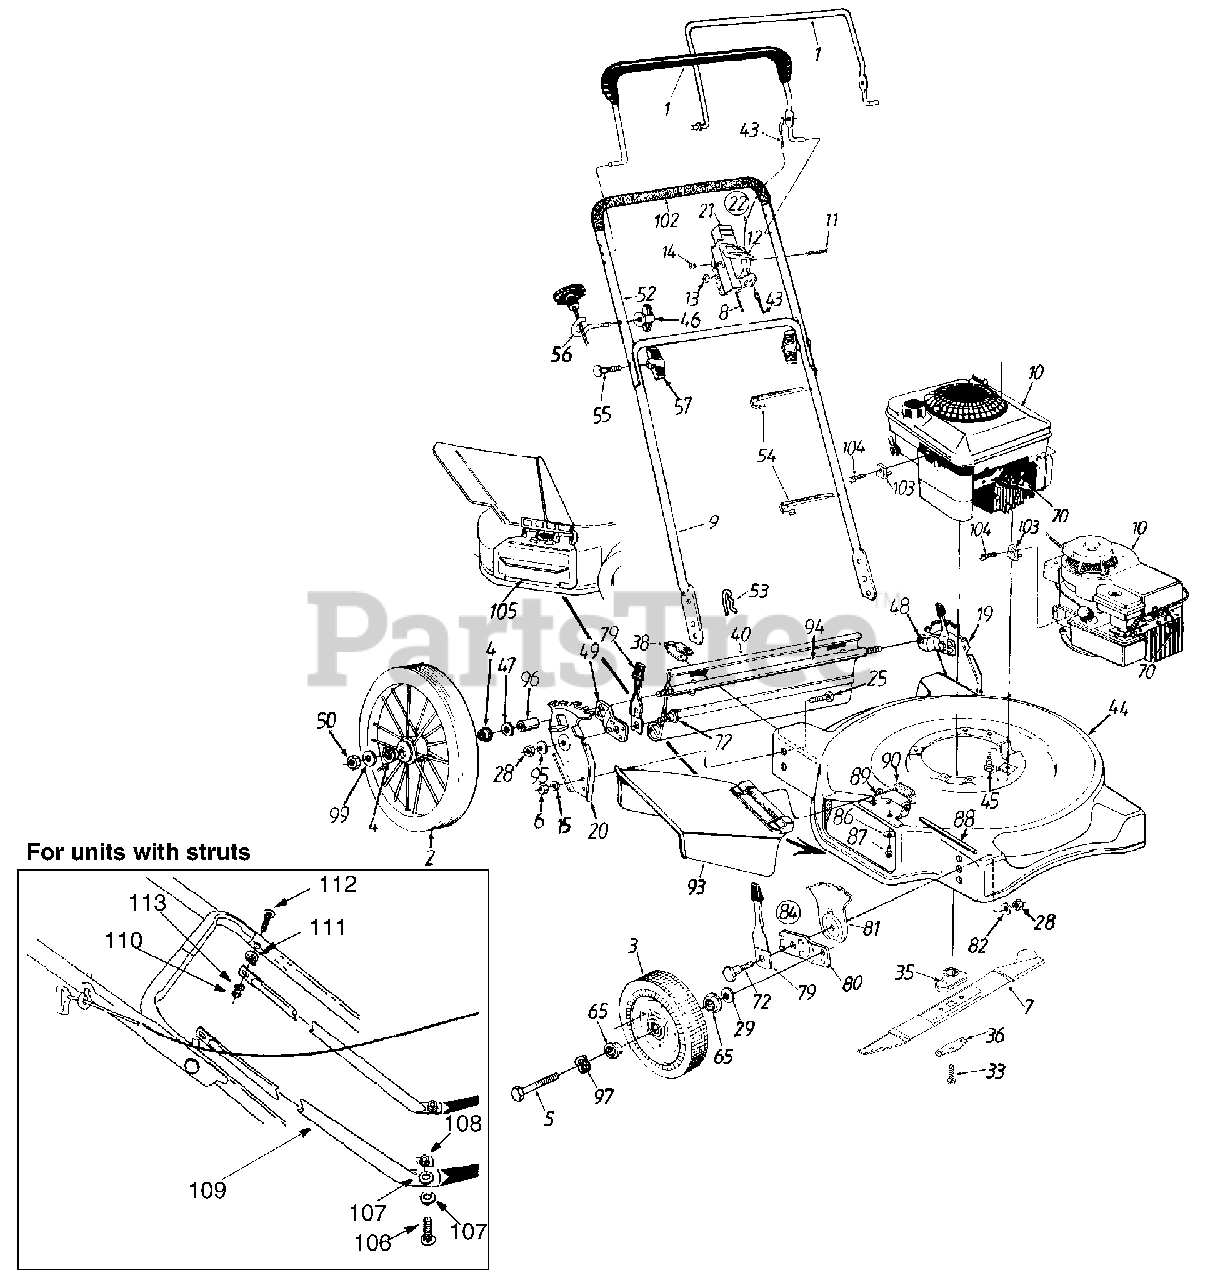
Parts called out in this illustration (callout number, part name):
2	Rear Wheel Assembly - 8 Spoke - Oyster
2	Rear Wheel Assembly - Aero Gray w/Ball Brgs.
2	Rear Wheel Assembly - Steel Spoke w/Ball Bearings
3	Front Wheel Assy Wheels w/o Bearings - (Gray) Bar Tread
3	Front Wheel Assy Wheels w/o Bearings - (Gray w/Hub Cap) Bar Tread
3	Front Wheel Assy Wheels w/o Bearings - (Beige) Bar Tread
3	Front Wheel Assy Wheels w/Plastic Brgs. - Aero Gray Bar Tread
3	Front Wheel Assy Wheels w/Plastic Brgs. - White "T" Tread
3	Front Wheel Assy Wheels with Ball Brgs. - Gray "T" Tread
3	Front Wheel Assy Wheels with Ball Brgs. - Gray "S" Wave Tread
3	Front Wheel Assy Wheels with Ball Brgs. - Gray Link Tread
4	Bearing
5	Front Axle Bolt
6	Hex Nut 3/8-24 Thd.
7	Blade 22"
8	Throttle Control Wire 51"
10	Engine
11	Oval C-Sunk Mach. Scr.
12	Throttle Lever
13	Spring Lever
14	Hex Lock Nut 1/4-20 Thd.
22	Throttle Box Comp.
25	Ribbed Neck Bolt 3/8-24 x 80"
28	Hex Nut 3/8-16 Thd.
29	Bell Washer
33	Hex Bolt 3/8-24 x 1.5"
35	Blade Adapter Kit
36	Blade Bell Support
38	Hinge Clip
40	Rear Flap Ass'y.
43	Control Cable - 39"
46	Handle Knob 1/4-20 Thd.
47	Wave Washer
48	Pivot Bar—L.H.
49	Pivot Bar—R.H.
50	Hex Jam Nut 3/8-16 Thd.
54	Cable Tie
55	Curved Hd. Bolt 5/16-18 x 2"
56	Rope Guide
57	Hand Knob
70	Spark Plug Boot
72	Shoulder Bolt
79	Spring Lever Assembly w/ knob
80	Pivot Bar
81	Height Adj. Plate
82	Bell Washer
84	Front Height Adjustment Assembly Comp.-R.H.
86	Bell Washer
87	Hex Washer Head Tap Scr. 1/4-20 x .5"
88	Hinge Pin
89	Adapter Plate
90	Torsion Spring
93	Chute Deflector Ass'y.
94	Rear Axle
95	Bell Washer
96	Spacer
97	Wave Washer
99	Flat Washer
102	Foam Grip
103	Casing Clamp
104	Hex Washer Head Tap Scr. #10-32 x .62"
105	Mulching Baffle
106	Hex Bolt 1/4-20 x .620 Gr.5
107	Bell Washer
108	Hex Nut 1/4-20
111	Saddle Washer
112	Hex Bolt 1/4-20 x .625 Gr.2
113	Lock Washer
